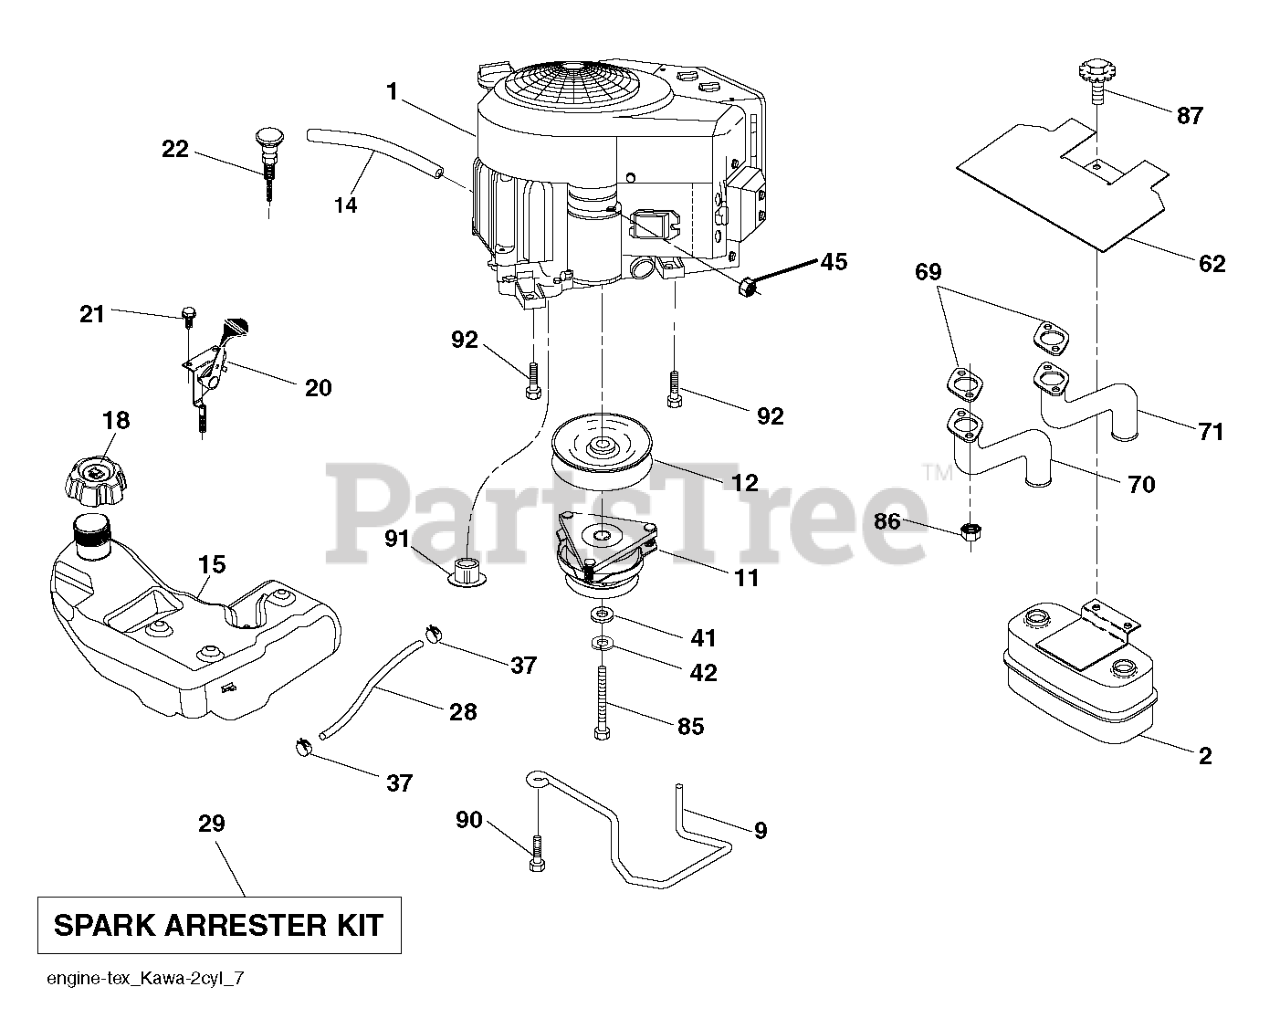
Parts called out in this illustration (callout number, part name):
2	MUFFLER.TWIN.CYL.LOW.TONE
9	KEEPER.BELT.ENGINE.4.2
11	CLUTCH.ELECTRIC.LT.48"*
12	PULLEY.ENGINE.TUFFTORQ
14	TUBE, DRAIN OIL ASM.
15	TANK.FUEL.4GAL
18	RP CAP FUEL
20	THROTTLE CABLE
21	SCREW.#10 X 0.750.BOS
22	CONTROL.CHOKE.ERGO.PUSH-IN.BLA
28	REPL BY 532 00 85-43
29	KIT.SPARK ARRESTOR 794945 B&S
37	HOSE CLAMP
42	LOCKWASHER
45	NUT
62	SHIELD.HEAT.MUFFLER
70	TUBE.EXHAUST.LH.FR961/FR730
71	TUBE.EXHAUST.RH.FR961/FR730
85	BOLT HEX 7/16-20X4-1/4"
86	NUT.HEX.FLANGE.TOPLOCK
87	BOLT.5/16-18UNCX1.W/SEMS.BLK
90	SCREW 3/8-16X1
91	BUSHING.1.375OD
92	SCREW 3/8-16X1
